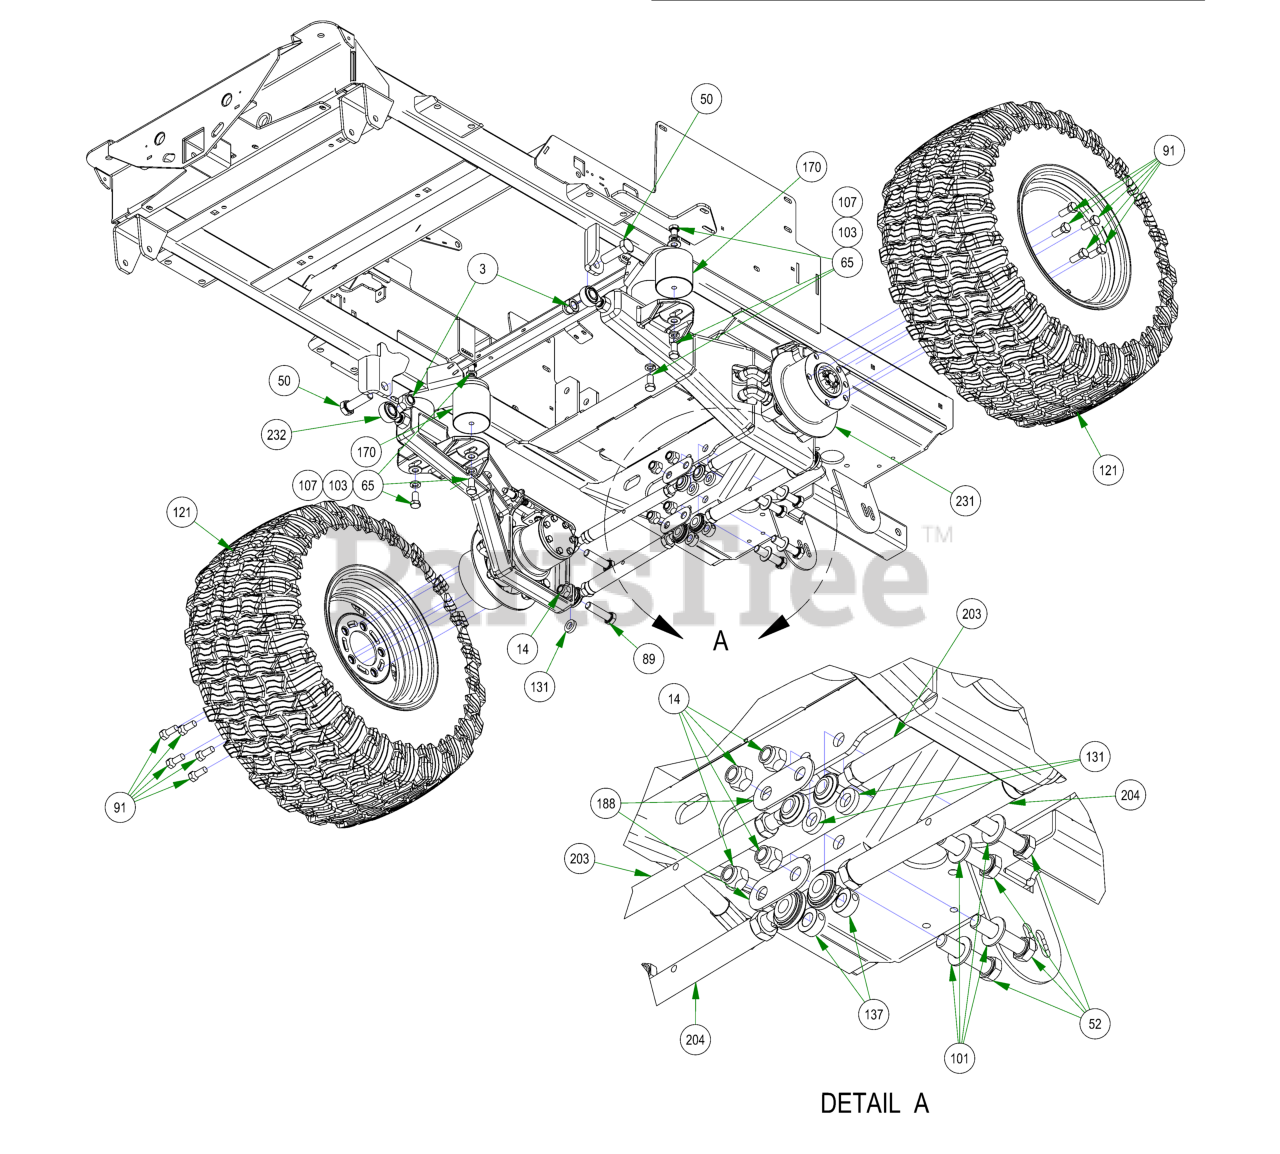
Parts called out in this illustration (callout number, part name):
3	3/4-10 NYLON INSERT LOCKNUT ZINC
14	5/8-11 NYLON INSERT LOCKNUT ZINC
50	3/4-10 X 2-1/2 HEX CAP SCREW (GR.5) ZINC
52	5/8-11 X 2-3/4 HEX CAP SCREW (GR.5) ZINC
65	1/2-13 X 1 HEX CAP SCREW (GR.5) ZINC
89	5/8-11 X 2-1/2 HEX CAP SCREW (GR.5) ZINC
91	1/2-20 x 60° Lug Bolts Zinc Grade 8
101	5/8" Flat Washer SAE Spec Grade 8
103	1/2 SPLIT LOCKWASHER (GR.8) ZINC/YELLOW
107	1/2 SAE FLAT WASHER (1-1/16" OD) GR.8 ZINC YELLOW
121	2019 Assy-26x12-12 Reaper Turf -10.5" Rim
131	Spacer 1.125OD x .625 ID x .250 Length
137	5/8 SOLID SHAFT COLLAR (W/1 SET SCREW) ZINC
170	Vibration Mount-Blue Dot
188	2019 Suspension Gusset Outlaw
203	2019 Suspension Radius Rod Assembly
204	2019 Suspension Radius Rod Assembly
231	2019 Renegade Trailing LH Arm Assy
231.4.1	1" Castle Nut for HydroGear Wheel Motor
231.4.2	Woodruff Key
232	2019 Renegade Trailing RH Arm Assy
232.4.1	1" Castle Nut for HydroGear Wheel Motor
232.4.2	Woodruff Key
235	2022 Horizontal Diesel Frame
